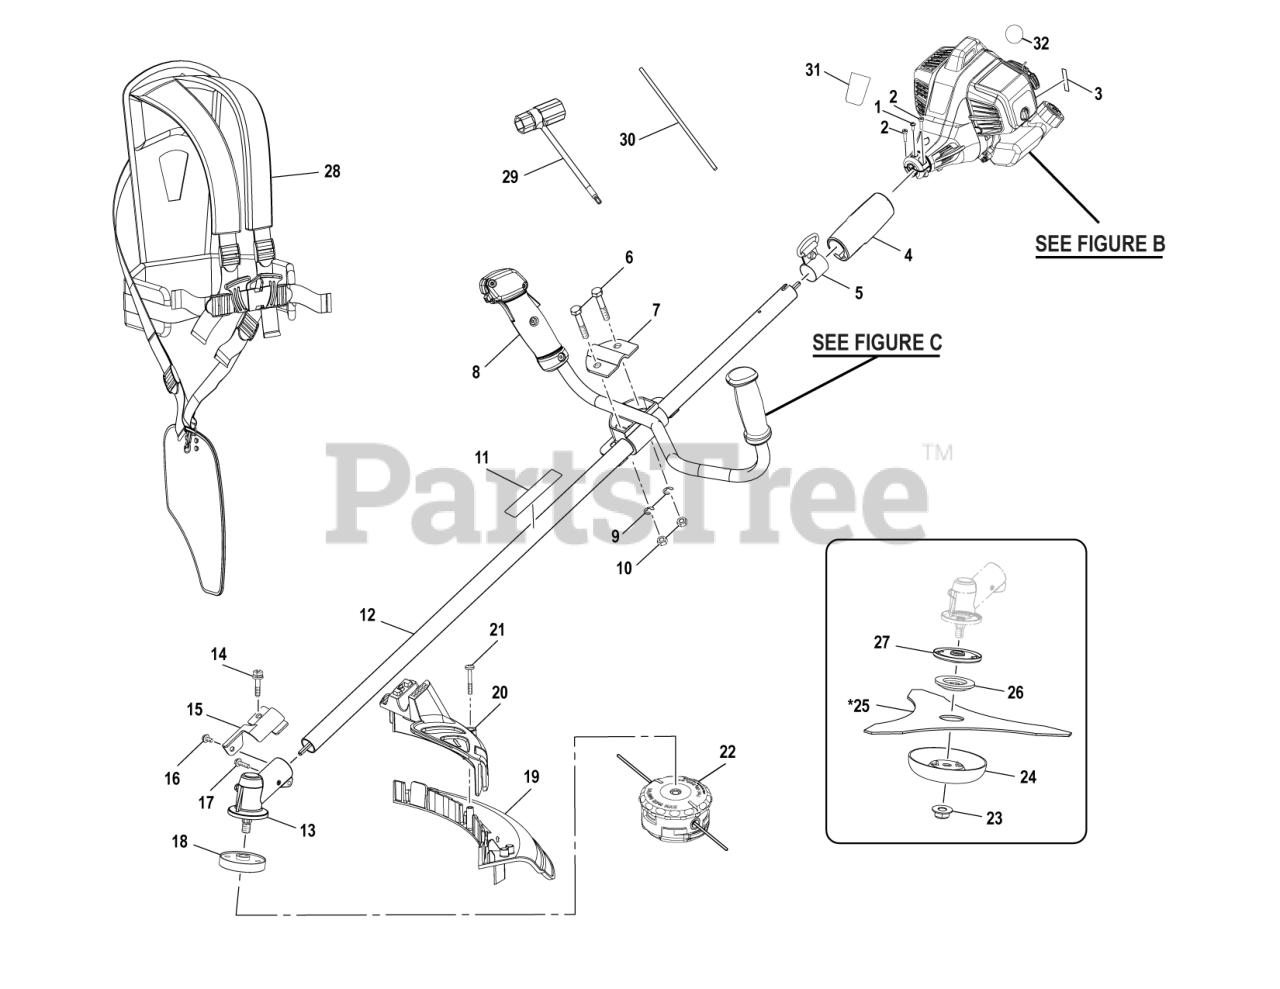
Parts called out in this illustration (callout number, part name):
3	LABEL, CHOKE
4	GRIP, HANDLE
5	ASSY., HANGER
8	ASSY., HANDLE BAR
10	NUT, HEX
11	LABEL, WARNING ICONS
12	ASSY., BOOM
13	Gearbox Assembly (Inc. Key Nos. 18, 26 & 27)
14	SCREW W/WASHERS
18	ADAPTOR W/FLANGE, TRIMMER HEAD
19	DEFLECTOR, GRASS
20	GUARD, BRUSH CUTTER
22	String Head Assembly
23	NUT, FLANGE LOCK
25	Optional Tri-Arc Blade
26	WASHER, FLANGE (SMALL)
27	ASSY., FLANGE WASHER
28	HARNESS, SHOULDER
29	WRENCH, SPARK PLUG
30	PIN, LOCKING
31	LABEL, FRONT LOGO
32	LABEL, STARTER ASSY.
